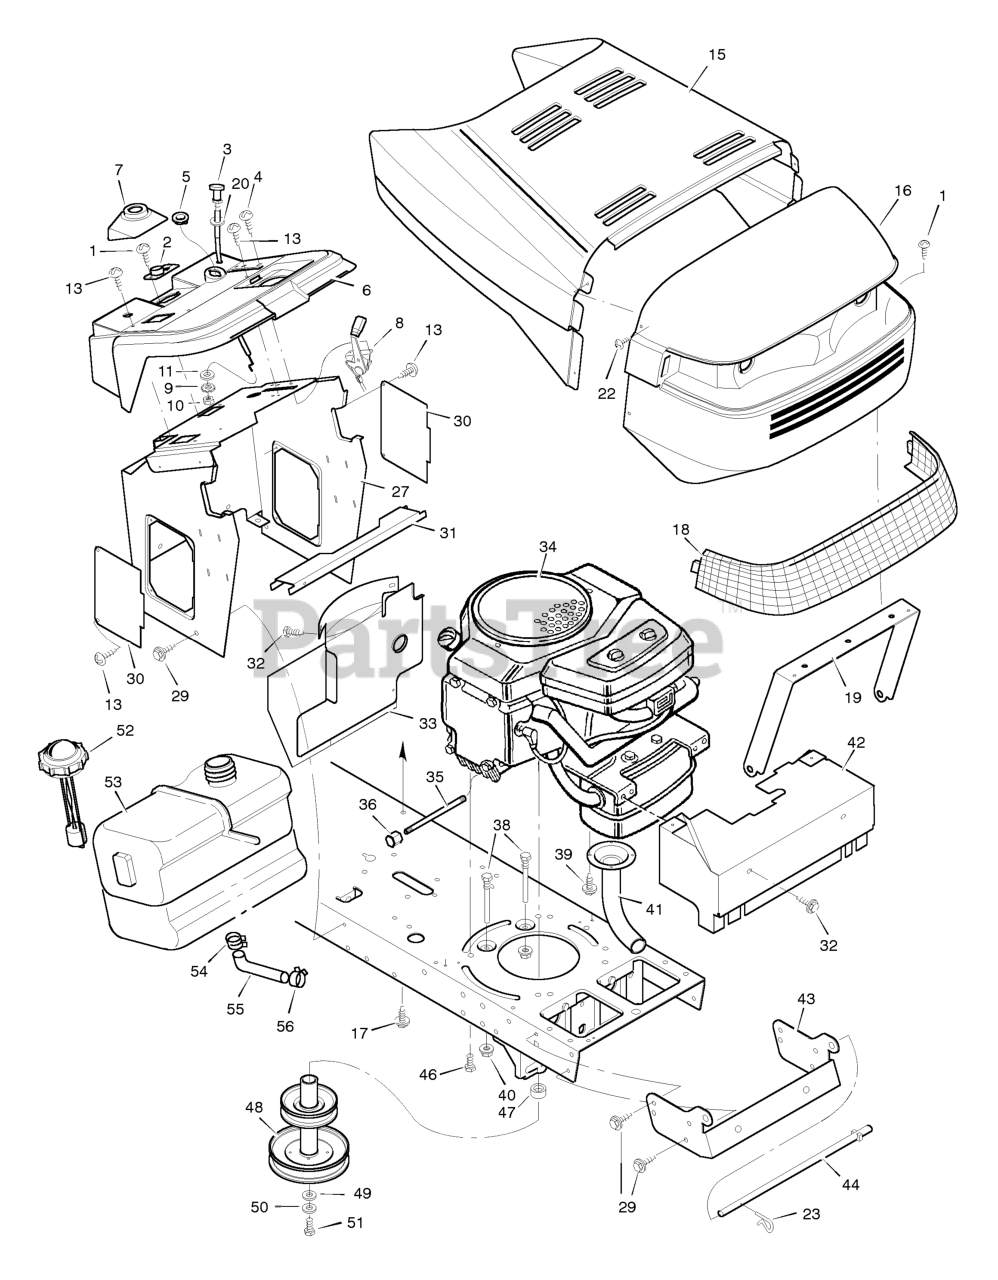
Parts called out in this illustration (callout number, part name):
2	Bearing, Steering Post
3	Cable, Choke
5	Bushing
7	Support, Bellows
8	Throttle Control
9	Lockwasher
10	Nut, Hex
13	Screw
16	Grille
19	Brace, Grille
20	Washer
23	Pin, Hair
27	Console Assembly
30	Panel, Side Access
31	Support, Fuel Tank
32	Screw
33	Baffle, Rear Heat
34	Engine *
35	Oil Drain Extension
36	Oil Drain Cap
38	Guide, Belt
40	Locknut, Flange
41	Pipe, Exhaust
42	Shield, Heat
43	Support, Grille
44	Rod, Pivot
46	Bolt, Hex
47	Spacer, Engine
48	Pulley Assembly, Stack
50	Lockwasher
51	Bolt, Hex
52	Cap, Fuel
53	Fuel Tank
54	Clamp, Hose
55	Fuel Line
56	Clamp, Hose
